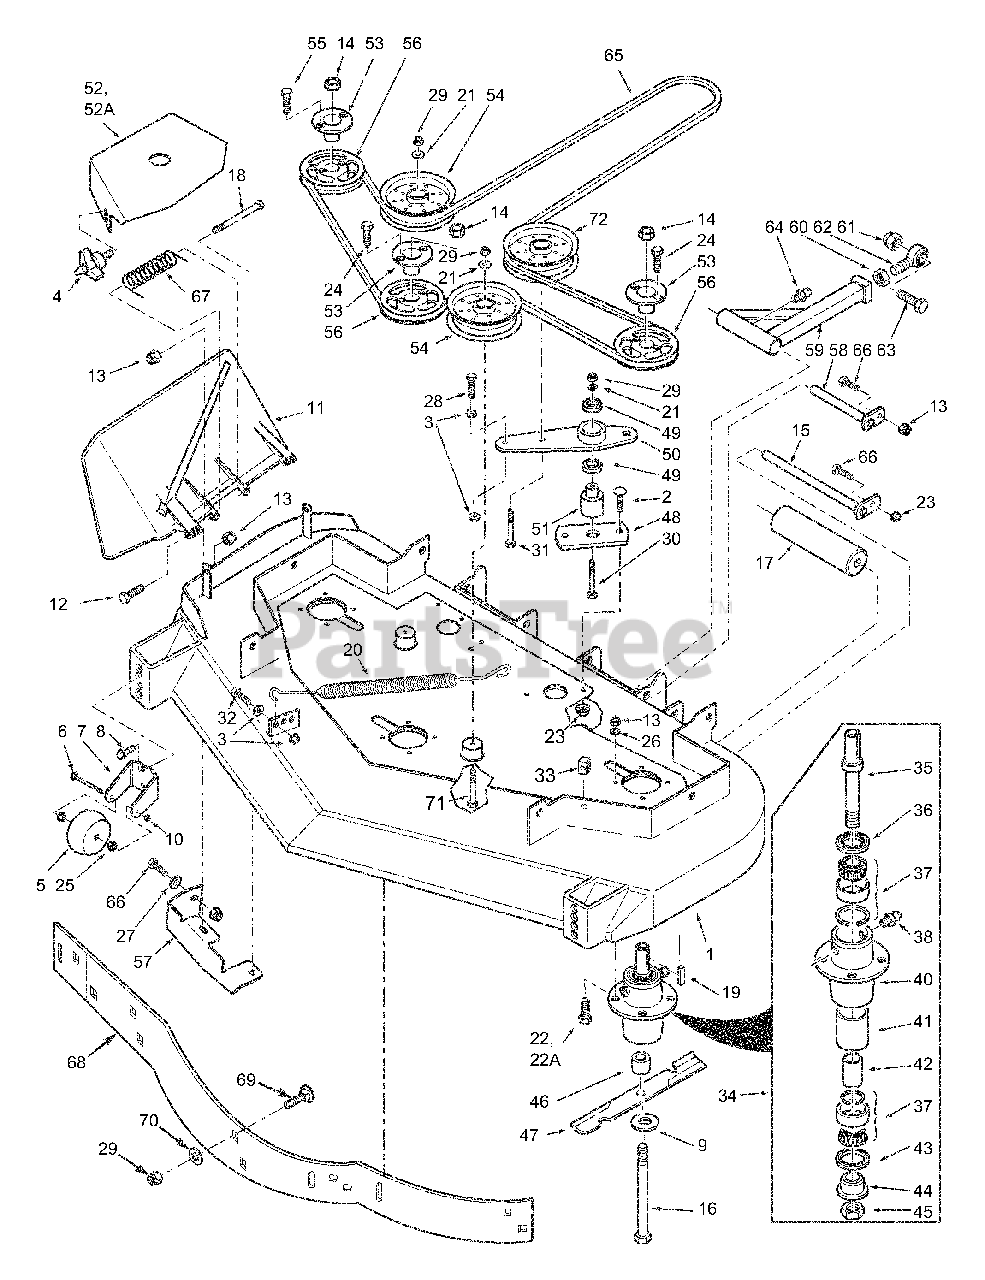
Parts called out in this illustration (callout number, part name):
1	Cutter Deck Advantage
2	Bolt, Carr. 5/16-18 x 1"
3	Nut, 3/8-16 Serrated Flange
4	Wing Nut, 3/8-16
5	Anti-Scalp Wheel
6	Bolt, Carriage 3/8-16 x 4"
7	Bracket, Anti-Scalp Wheel
8	Bolt, Serrated Flange 3/8-16 x 1"
9	Flatwasher, 5/8" Hardened
10	Locknut, 3/8-16 Center Lock
11	Discharge Chute
12	Bolt, Hex Head 5/16-18 x 1-1/2", Rear
13	Nut, Elastic Stop 5/16-18
14	Nut, 5/8-11 UNC
15	Shaft, Roller
16	Bolt, Hex Head 5/8-11 x 9-1/2"
17	Roller, Rear
18	Bolt, Hex Head 5/16-18 x 4-3/4"
19	Key, 1/4 x 1/4 x 2"
20	Spring, Idler
21	Flatwasher, 3/8"
22	Bolt, Hex Head 5/16-18 x 1-1/2"
22A	Bolt, Hex Head 5/16-18 x 1-3/4"
23	Nut, Serrated Flange 5/16-18
24	Bolt, Hex Head 1/2-20 x 3/4"
25	Bushing, .376 ID Oilite
26	Lockwasher 5/16"
27	Flatwasher 5/16"
28	Bolt, 3/8-16 x 1-1/2" Grade 8
29	Nut, Elastic Stop 3/8-16
30	Bolt, Hex Head 3/8-16 x 2-1/2"
31	Bolt, Hex Head 3/8-16 x 3.25"
32	Bolt, Hex Head 3/8-16 x 1-1/2 Grade 8
33	U-Nut, 3/8-16
34	Spindle Assembly
35	Shaft, Spindle
36	Seal Upper
37	Bearing Assembly
38	Grease Fitting
40	Housing, Spindle
41	Spacer, Outside
42	Spacer, Inside
43	Seal, Lower
44	Bushing, Bottom
45	Nut, Special 1-1/16 - 18
46	Spacer, Spindle
47	Cutter Blade 16.5"
48	Pivot, Idler Base
49	Bearing
50	Idler Arm Assy.
51	Idler Pivot
52	Belt Cover LH (48A)
52A	Belt Cover RH (48A)
53	Hub, Tapered 1-1/8" Bore
54	Pulley, Idler 5.0"
55	Bolt, Hex Head 1/4-20 x 1"
56	Pulley 4.75"
57	Turbo Baffle, Bolt On
58	Push Arm Shaft
59	Push Arm
60	Nut, 5/8-18 UNF
61	Nut, Elastic Stop 5/8-11
62	Rod End, 5/8 Male RH Thread
63	Bolt, Hex Head 5/8-11 x 4-1/2"
64	Grease Fitting, 90 Degree
65	Belt, Cutter Deck Drive (48A")
66	Bolt, Hex Head 5/16-18 x 1"
67	Spring, Discharge Chute
68	Baffle Weldment, 48A
69	Bolt, Carriage 3/8-16 x 1"
70	Flatwasher, 3/8-.391 x .938 x .105
71	Bolt, Hex Head 3/8-16 x 3-3/4"
72	Pulley, Idler 5" Dia
